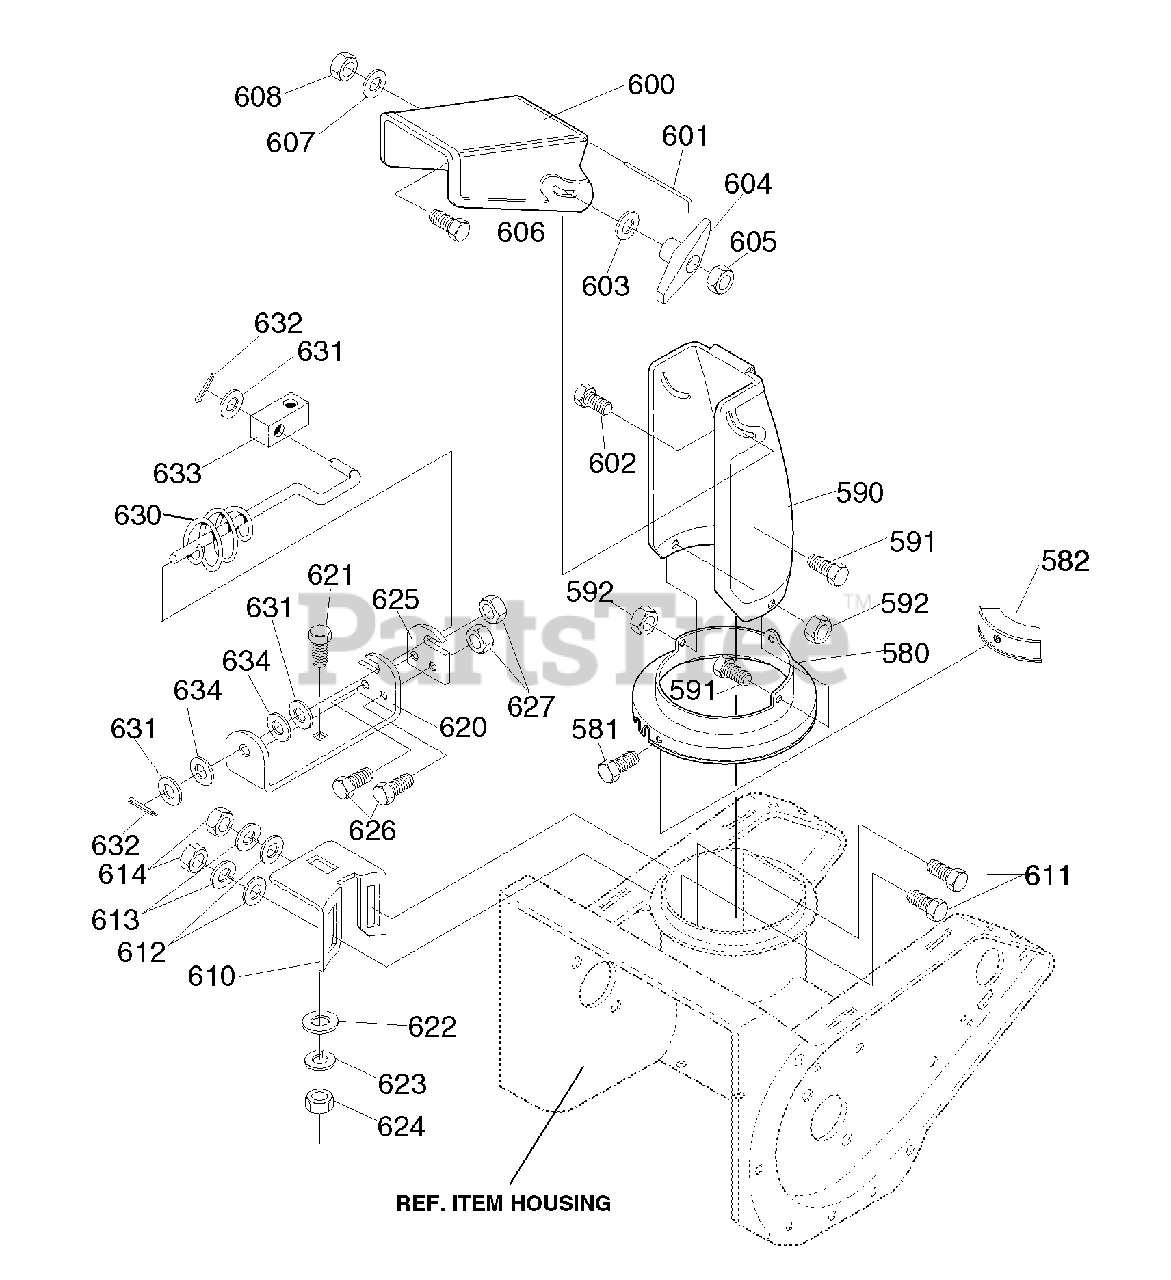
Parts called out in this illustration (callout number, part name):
580	RING, LOWER CHUTE
581	SCREW, 1/4-14 X .63 HWATAP
582	CLIP, CHUTE RING PLASTIC
590	CHUTE, LWR SRS 8HP
591	SCREW, 1/4-20 X .50 HHC
592	NUT, 1/4-20 WDFL MAC-LOCK
600	CHUTE, UPR SRS W/OHDLE
601	WIRE, HINGE 6.65 LG SR
602	BOLT, 5/16-18 X 1.25 CARR
603	WASHER, FLAT .344 X .69 X .065
604	KNOB, T 2BLADE W/516/18 NU
605	NUT, 5/16-18 REGHEX
606	SCREW, 5/16-18 X .75 SLTRMA
607	WASHER, FLAT .344 X .69 X .065
608	NUT, 5/16-18 REGHEXCTRLK
610	BRACKET, WORM ADJUST
611	BOLT, 5/16-18 X .75 CARR
612	WASHER, FLAT .344 X .69 X .065
613	WASHER, HVSPTLK
614	NUT, 5/16-18 REGHEXCTRLK
620	BRACKET, CHUTE ROD HOLDER
621	BOLT, 5/16-18 X .75 CARR
622	WASHER, FLAT .344 X .69 X .065
623	WASHER, HVSPTLK
624	NUT, 5/16-18 REGHEXCTRLK
625	PLATE, CHUTE ROD
626	SCREW, 1/4-20 X .50 HHC
627	NUT, 1/4-20 REGHEXCTRLK
630	ROD, ASSY CHUTE LWR
631	WASHER, FLAT .40 X .75 X .025
632	PIN, COTTER .090 DIAX .75 LG
633	BLOCK, PIVOT PLASTIC
634	WASHER, CURVED SPRING
